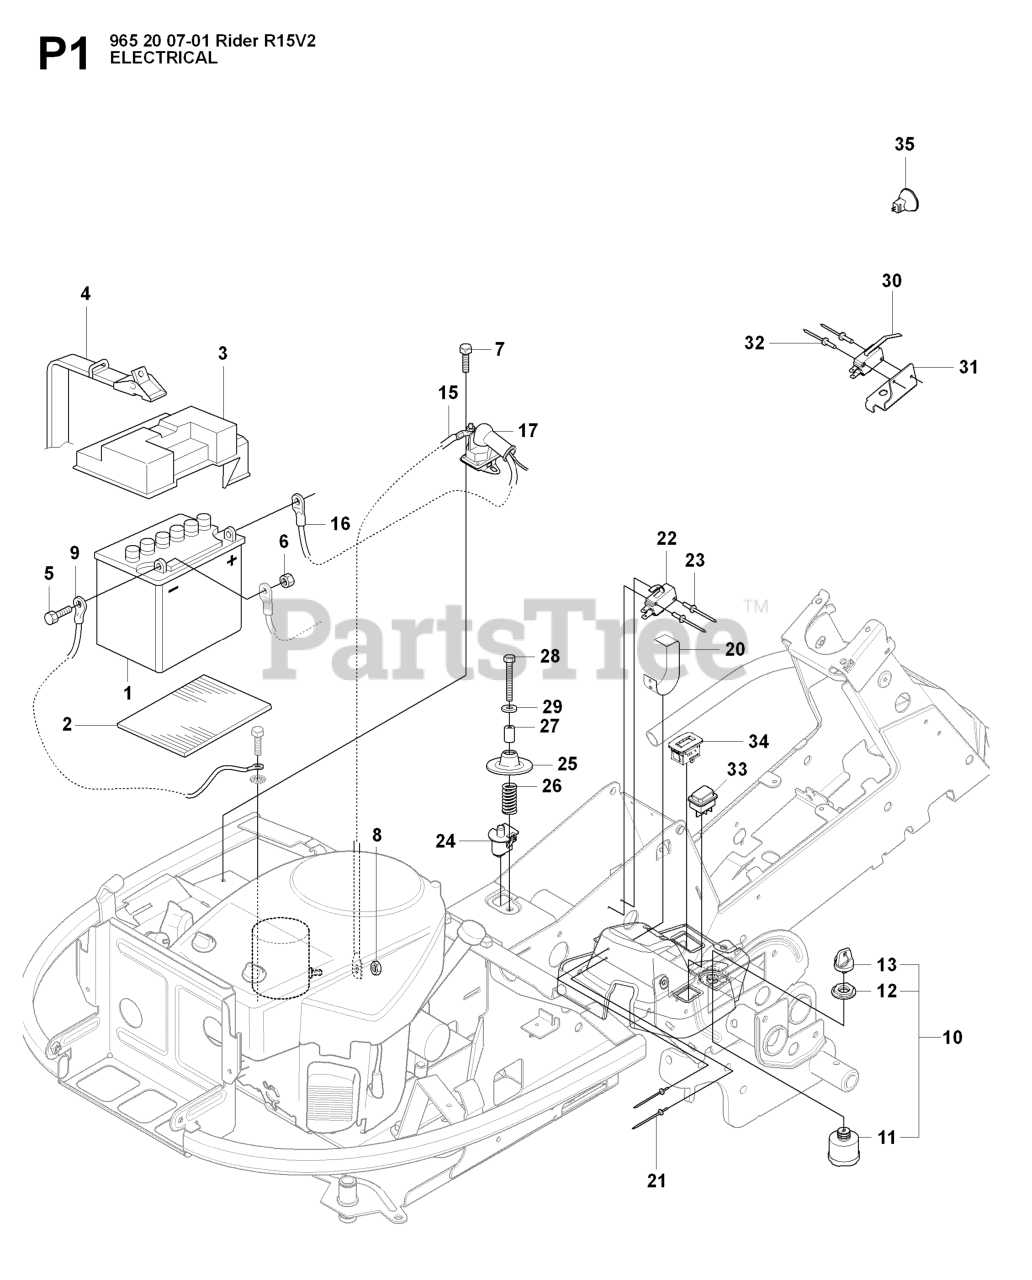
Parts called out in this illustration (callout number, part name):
1	BATTERY - DRY
10	IGNITION SWITCH
11	IGNITION SWITCH
13	IGNITION KEY
22	%BRAKER
27	SPACER TUBE
28	SCREW
29	WASHER BRB 8.4X17
30	RP MICRO SWITCH
